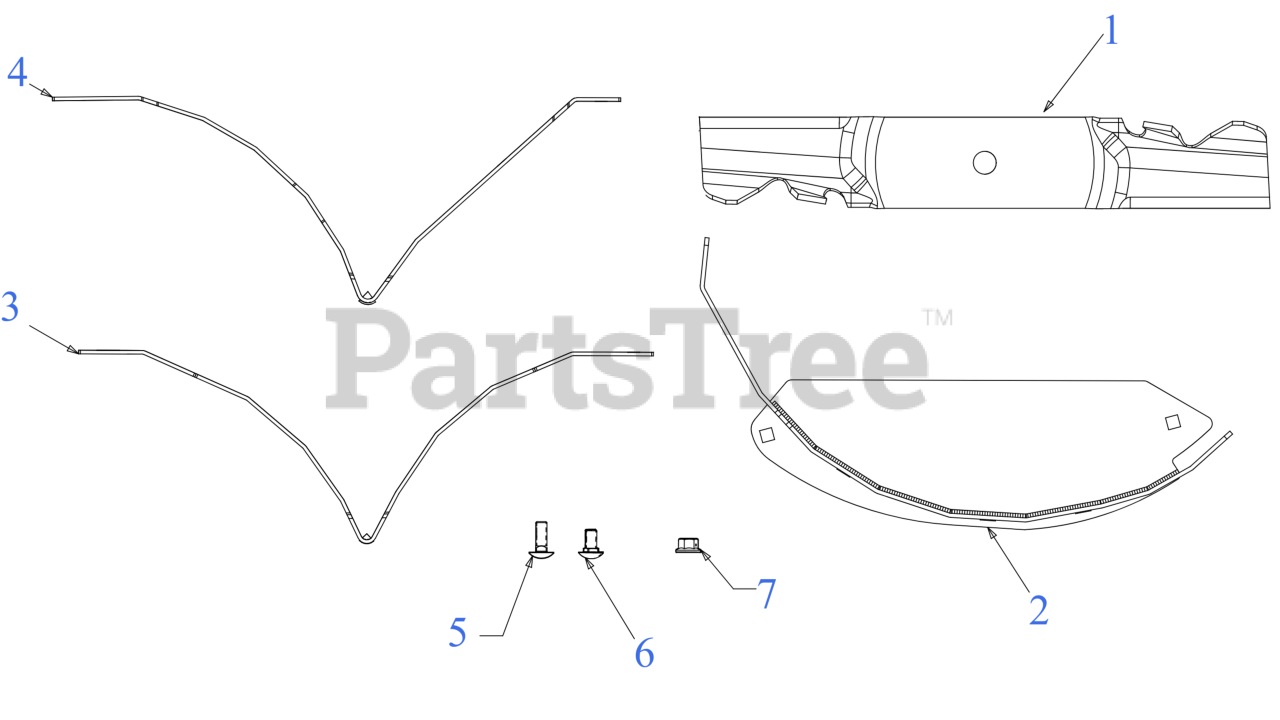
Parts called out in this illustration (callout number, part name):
1	19" XTREME BLADE
2	54" DISCHARGE MULCH BAFFLE
3	MULCH BAFFLE (LEFT)
4	MULCH BAFFLE (CENTER)
5	CARRIAGE BOLT 3/8-16 x 1.00 GR5
6	CARRIAGE BOLT 3/8-16 x .75
7	NUT-CTRLCK FLG HEX
